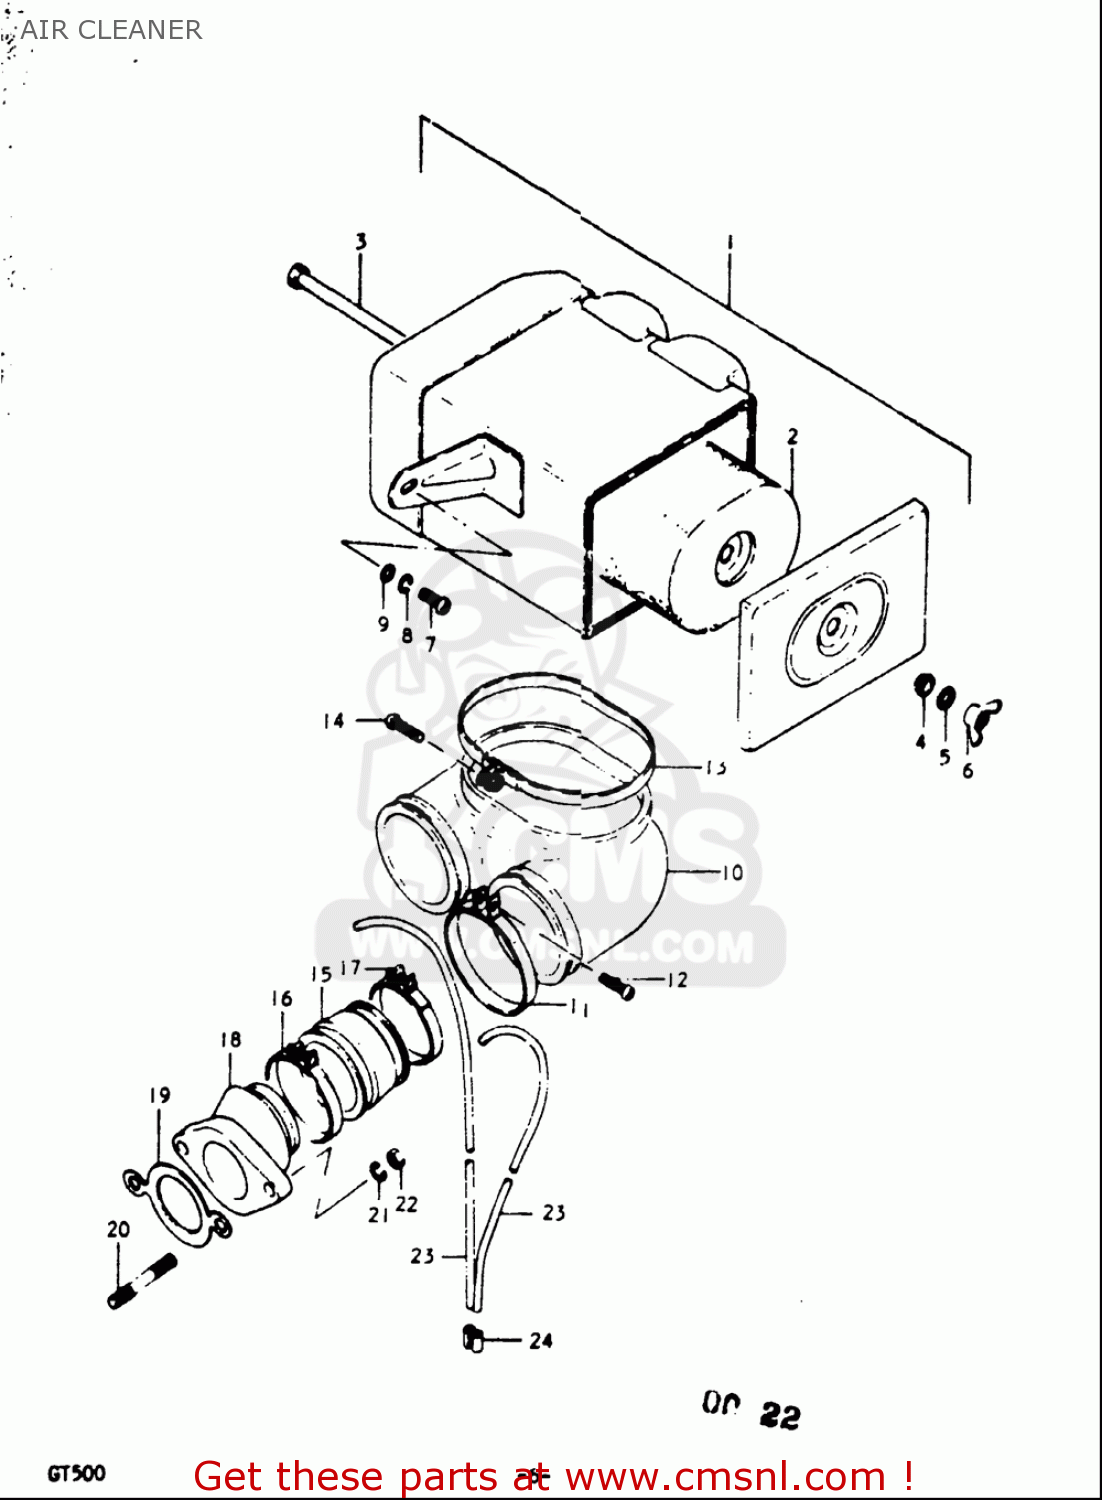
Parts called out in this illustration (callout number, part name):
2	FILTER ASSY,AIR CLEANER
5	WASHER
6	NUT
7	SCREW
8	WASHER,LOCK
9	WASHER
10	HOSE,CARBURETOR AIR INLET
11	CLAMP
12	SCREW
14	SCREW
15	PIPE,INTAKE
16	CLAMP
17	CLAMP
19	GASKET,CARBURETOR (NAS)
20	STUD 8X25
21	WASHER,LOCK
22	NUT
23	HOSE(3X5X600)
24	CLIP
